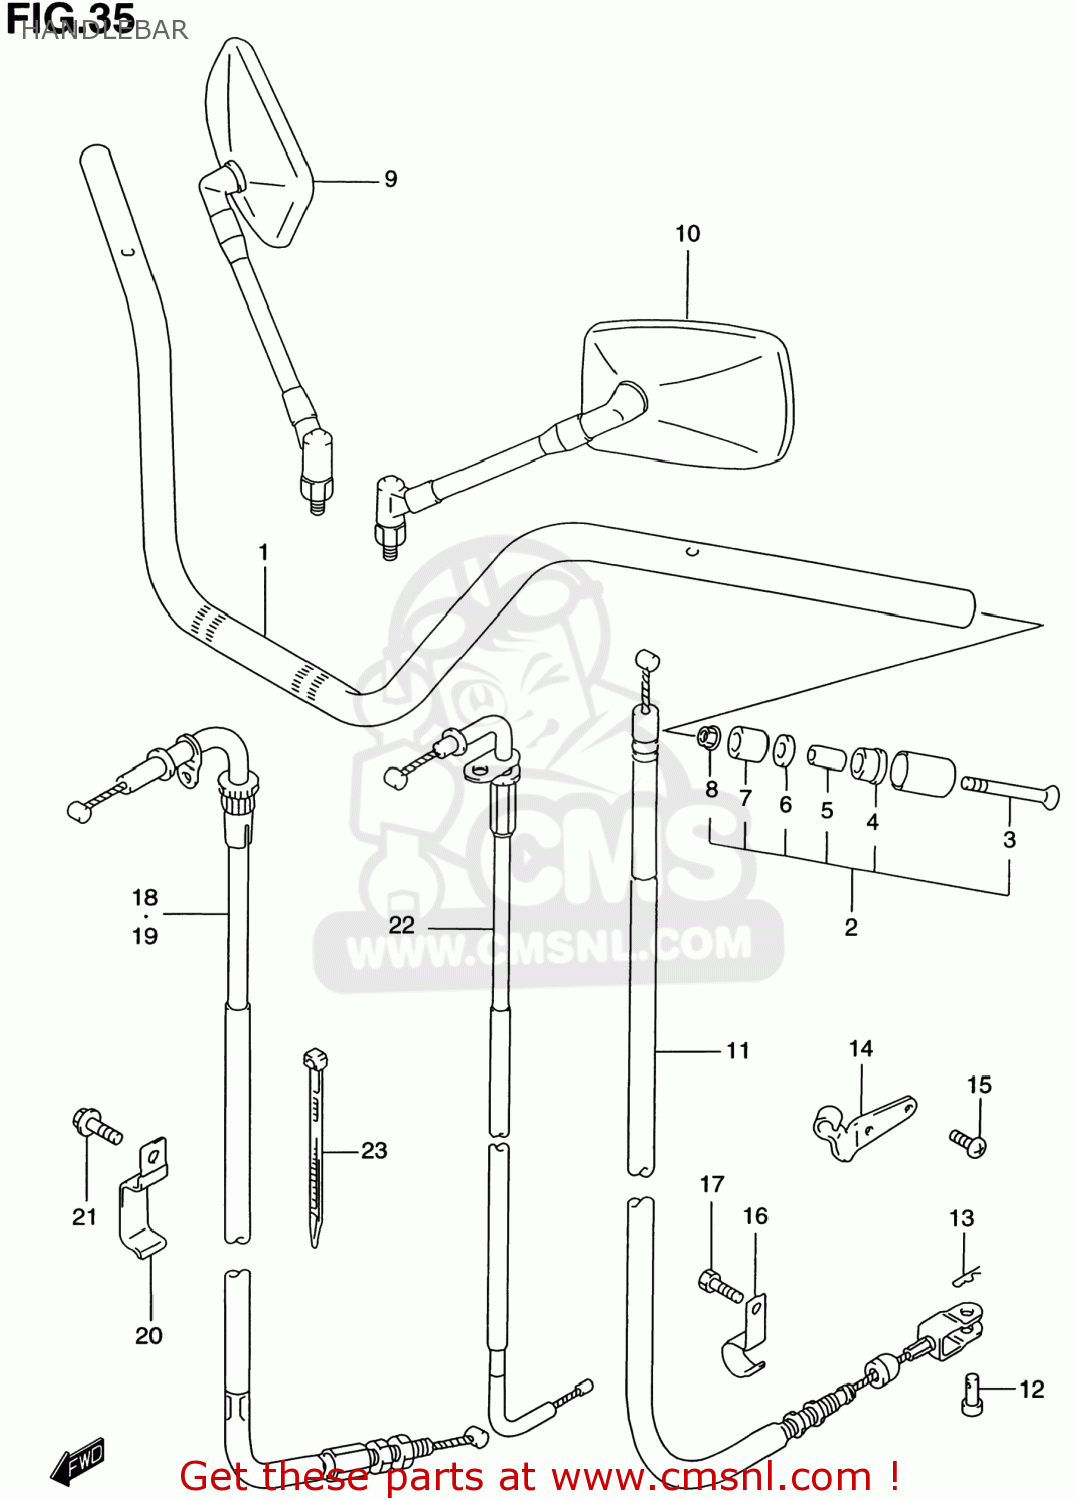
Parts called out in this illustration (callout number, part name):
1	HANDLEBAR
2	BALANCER SET,HANDLEBAR
3	SCREW(6X125)
4	EXPANDER,HANDLE BALANCER NO.2
5	SPACER,EXPANDER
6	WASHER(6.5X14X2)
7	EXPANDER,HANDLE BALANCER
8	NUT
9	MIRROR ASSEMBLY,REAR VIEW
10	MIRROR ASSEMBLY,REAR VIEW
11	CABLE ASSY,CLUTCH
12	PIN(L:13)
13	PIN
14	STOPPER,CLUTCH CABLE
15	BOLT
16	CLAMP,CLUTCH CABLE NO.1
17	SCREW
18	CABLE ASSY,THROTTLE NO.1
19	CABLE ASSY,THROTTLE NO.2
20	CLAMP
21	BOLT
22	CABLE,STARTER
23	CLAMP(L:125)
